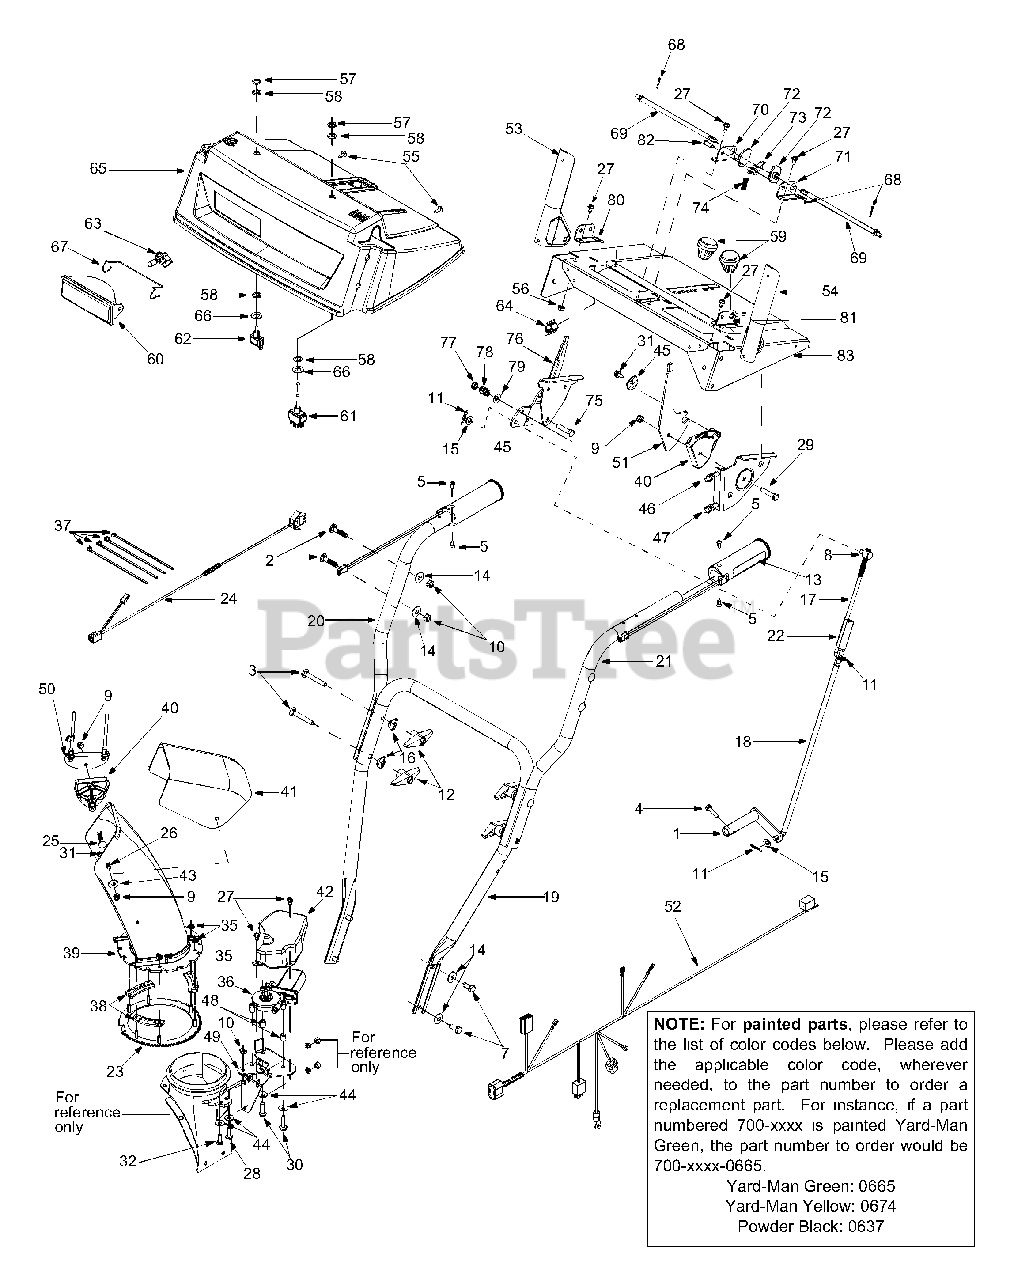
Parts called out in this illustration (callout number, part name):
2	Carriage Bolt 5/16-18 x 1.5"
3	Carriage Bolt 5/16-18 x 2.25"
4	TT Screw 1/4-20 x 1"
5	C-Sunk Screw #10-16x 0.625"
7	Hex Screw 5/16-18 x .75"
8	Ferrule
10	Hex Nut 5/16-18
11	Cotter Pin
12	Handle Knob
13	Heated Grip
14	Lock Washer
15	Flat Washer
16	Saddle Washer
17	Shift Rod: Upper
18	Shift Rod: Lower
23	Gear Assembly: Ring
24	Electric Harness: Lower
25	Carriage Bolt: 5/16-18 x 1.5"
26	Carriage Bolt: 5.16-18 x .750"
27	TT Screw: 1/4-20 x 0.5"
28	TT Screw: 5/16-18 x 1"
29	Hex Screw: 5/16-18 x 1.5"
30	TT Screw: 5/16-18 x 1.25"
31	Hex Screw AB:1/4-14 x 0.625"
32	Hex Screw: 5/16-18 x .75"
35	Hex Flange Lock Nut
36	Electric Motor: Chute Crank
37	Cable Tie
38	Chute Flange Keeper
39	Lower Chute
40	Cable Guide: Chute Tilt
41	Upper Chute
42	Motor Cover: Chute Rotation
43	5/16 Washer
44	Belleville Washer
45	Special Washer
46	Control Cable
47	Control Cable
48	Spacer
52	Harness Assembly: Upper
53	Handle Eng. Assembly RH
54	Handle Eng. Assembly LH
55	Special Hex Screw
56	Hex Sems Nut: 1/4-20
57	Hex Nut
58	Lock Ring: Toggle Switch
59	Shift Knob
60	Lamp Housing
61	Toggle Switch: Double Throw
62	Toggle Switch: Single Throw
63	Halogen Lamp: 50W, 12V
64	Mounting Clamp
65	Handle Panel
66	Flat Washer
67	Headlight Retainer
68	Cotter Pin: 3/32 x .75
69	Cam Rod
72	Cam Handle Lock
73	Handle Lock Pawl
74	Compression Spring: .36 x 1.0
75	Hex Cap Screw: 3/8-24 x 1.5
78	Comp. Spring: .39 x .6 x .88
79	Bell Washer
82	Clevis Pin
